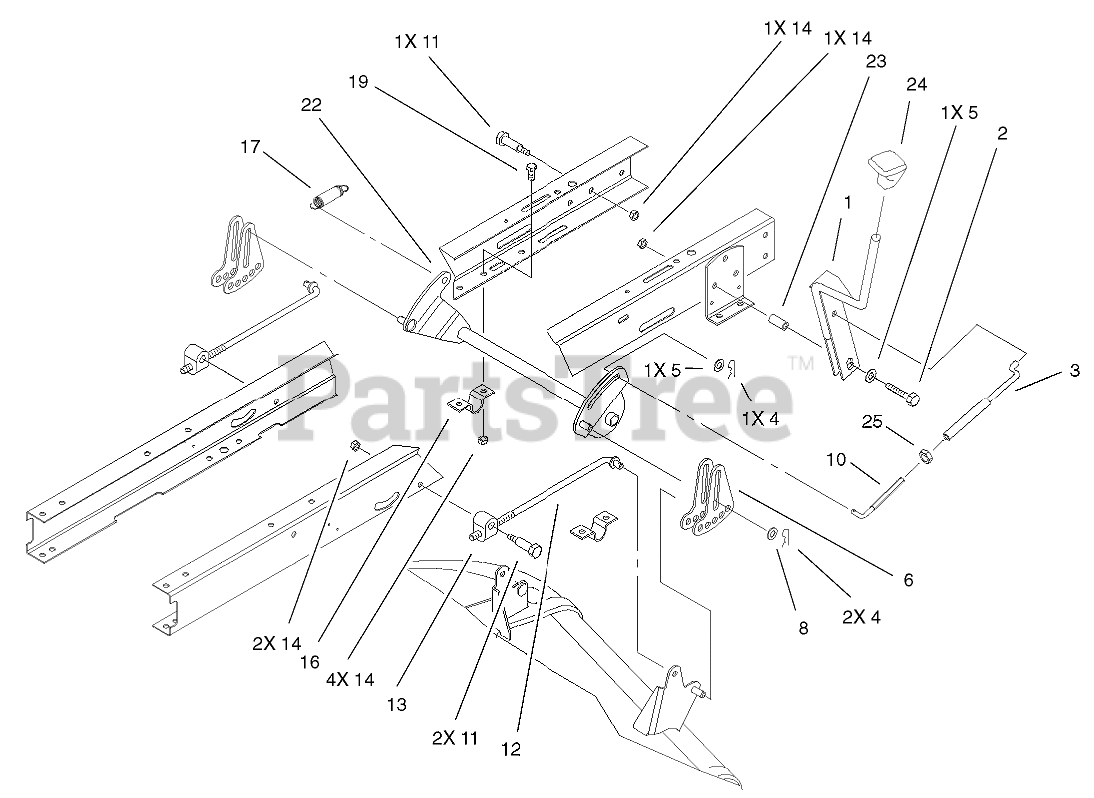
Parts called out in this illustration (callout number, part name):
1	HOC LEVER ASM
2	SCREW-HH
4	PIN-COTTER
5	WASHER-FLAT
6	LINK-ADJUSTING, HOC
8	WASHER-HARDENED
10	LINK-HOC
11	SCREW-SHOULDER, HH
12	ROD-HANGER, REAR
13	TRUNNION-HOC
14	NUT-LOCK, NI
16	CLAMP-PIVOT, HOC
17	SPRING-EXTENSION
19	SCREW-HH
22	PIVOT-HOC
23	SPACER
24	KNOB-SHIFT
25	NUT-JAM
